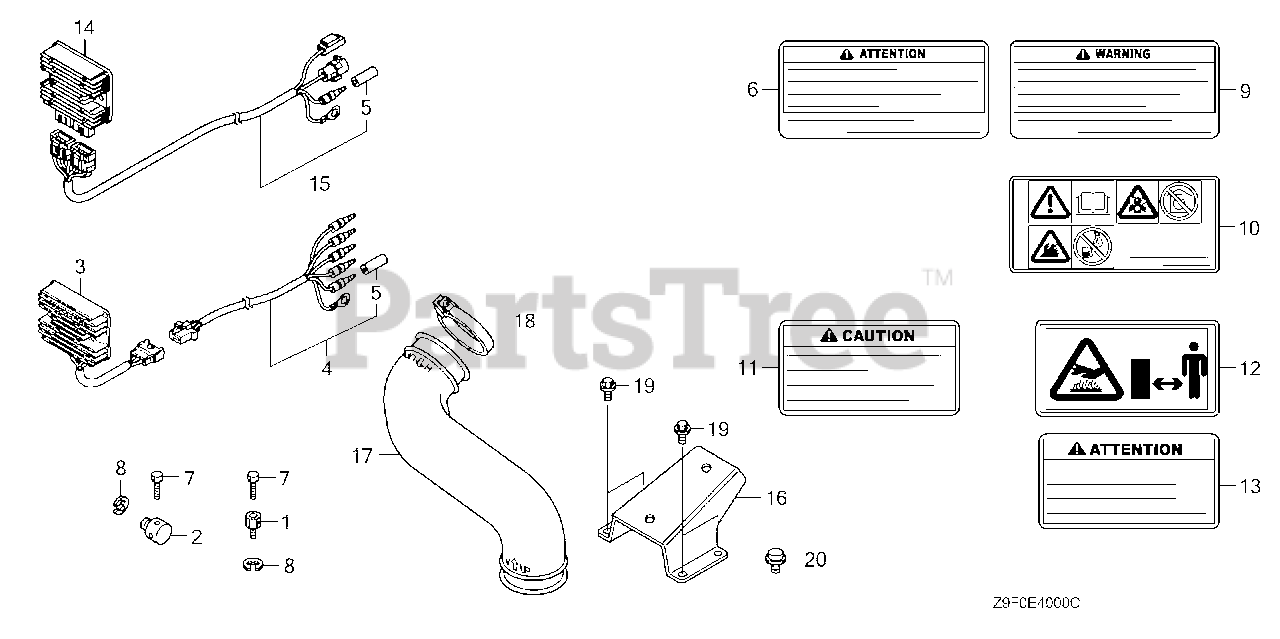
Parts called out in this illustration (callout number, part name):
1	HOLDER, WIRE
2	HOLDER, CABLE
6	MARK, OPERATOR CAUTION (FRENCH)(MADE IN JAPAN)
7	BOLT, RECESSED (4X6)
8	E-RING (5MM)
10	MARK, OPERATOR CAUTION (PICTOGRAPH)
11	MARK, EX. CAUTION (ENGLISH)
12	MARK, EX. CAUTION (PICTOGRAPH)
13	MARK, EX. CAUTION (FRENCH)
